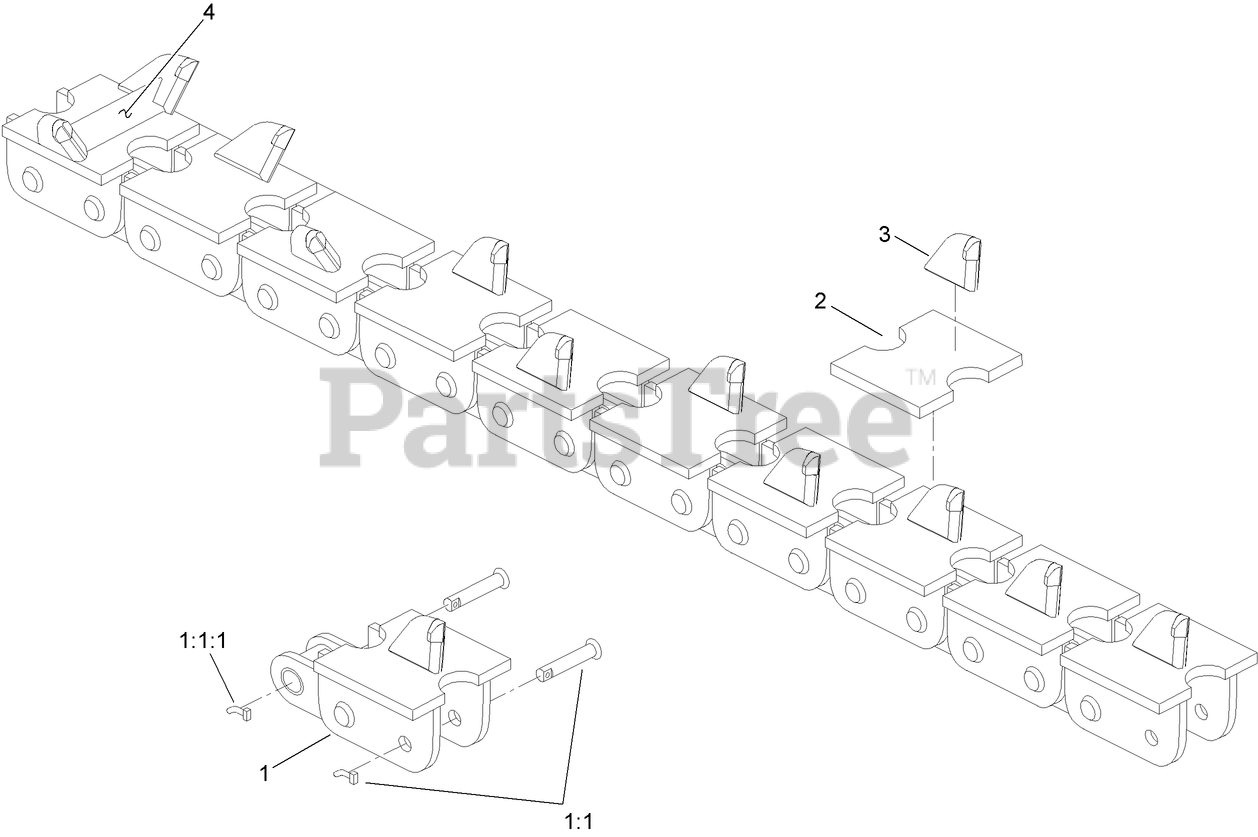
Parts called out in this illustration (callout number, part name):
1	CHAIN REPAIR LINK ASM
1:1	NOTCHED PIN AND KEEPER ASM
1:1:1	PIN-KEEPER
2	PLATE-H, WELD-ON
3	TOOTH-TERMINATOR, WELD-ON
4	DRAG-DIRT, WELD-ON (6.00)
